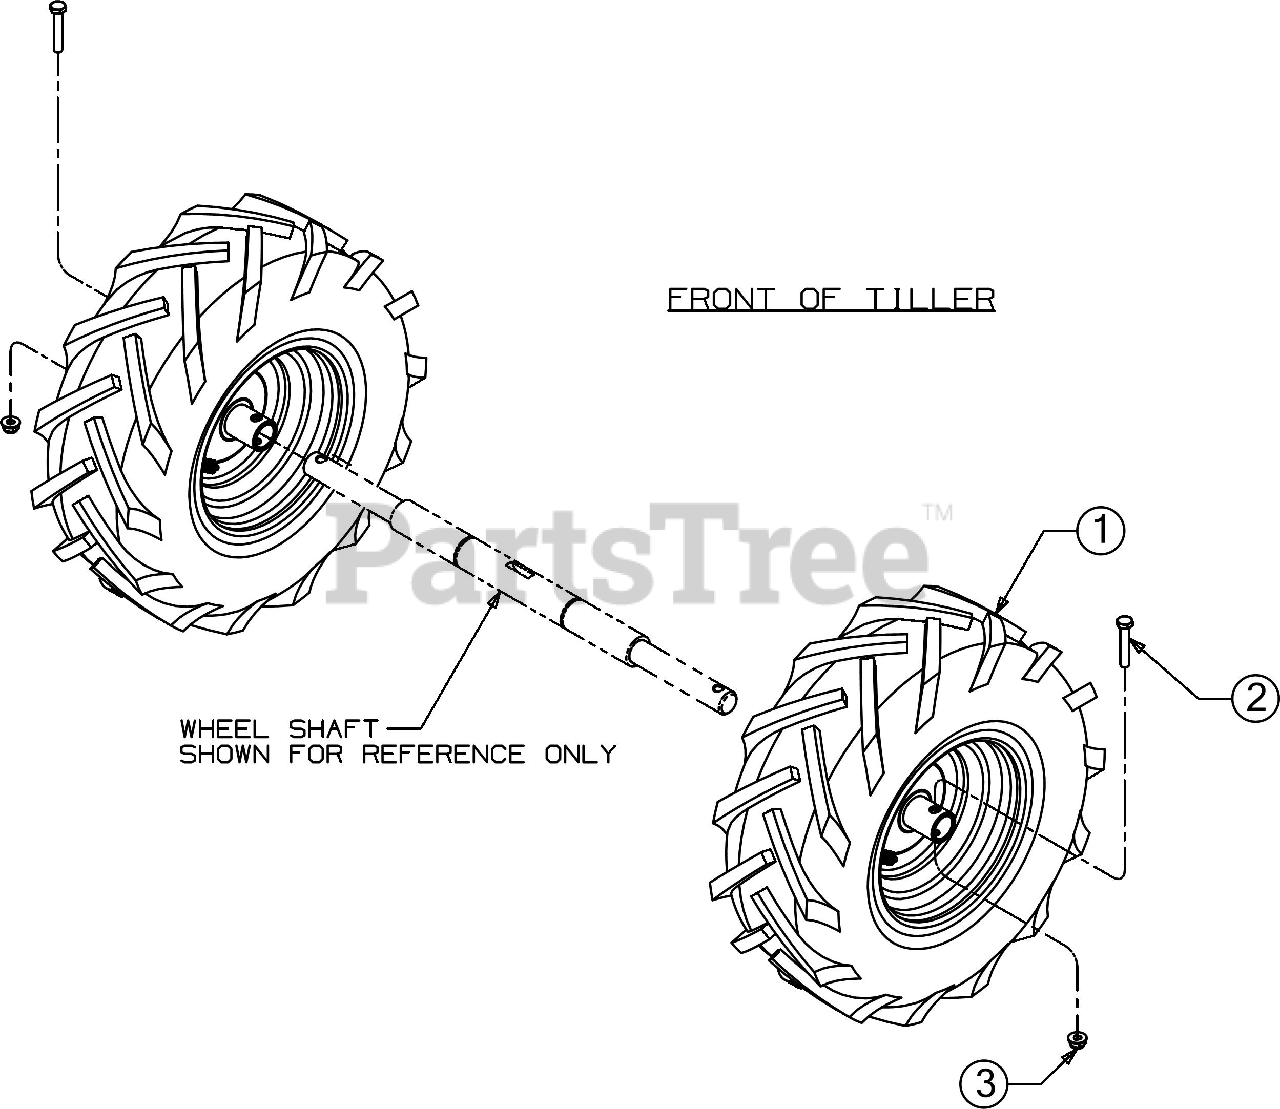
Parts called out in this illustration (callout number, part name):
1	WHEEL ASSEMBLY (13 X 5 X 6)
2	SCREW 1/4-20 X 1.50 GR8
3	FLANGE LOCK NUT
